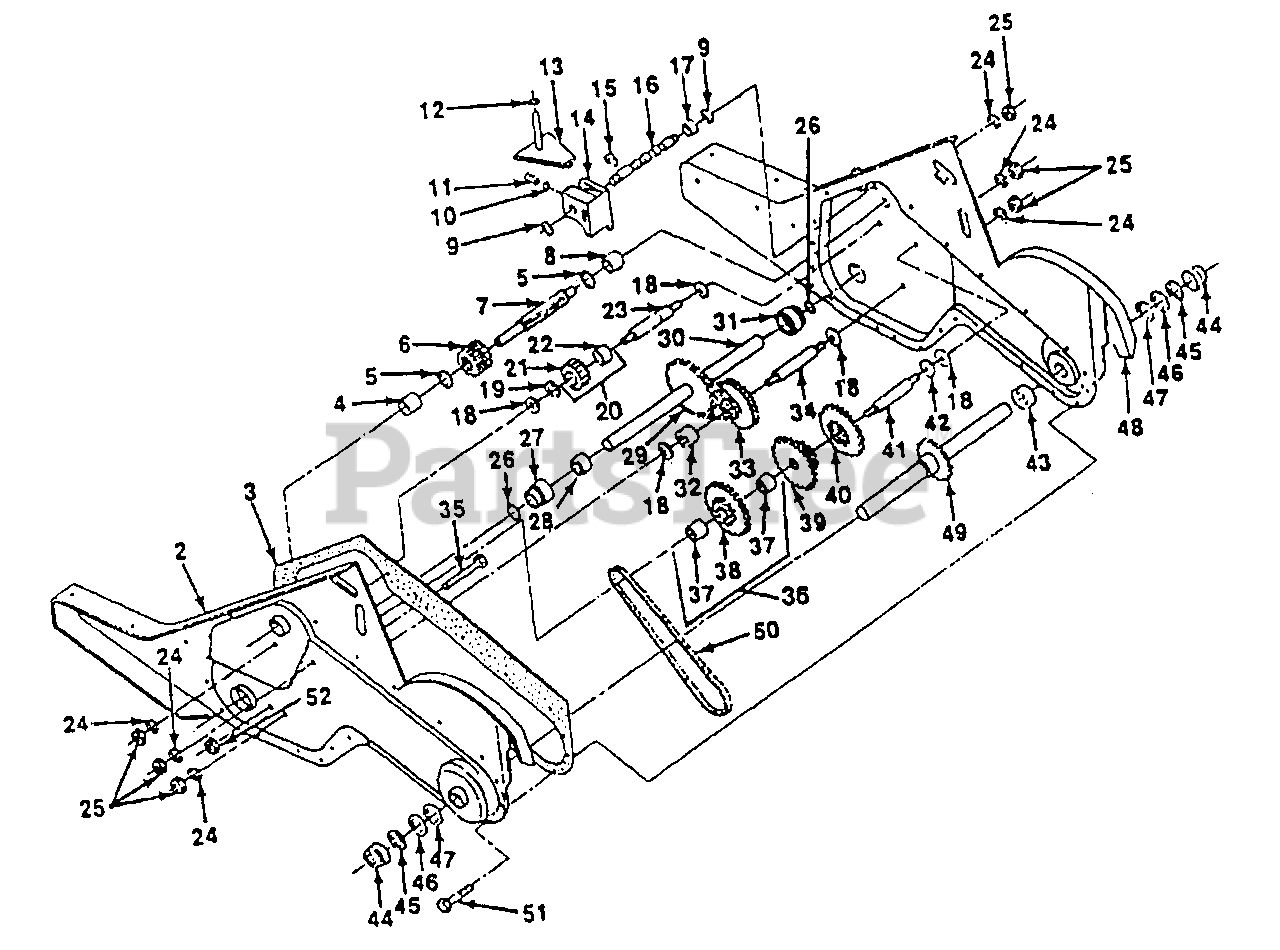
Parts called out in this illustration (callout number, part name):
1	Transmission Assembly (Inc. 2-52) (AYP part number)
2	Gearcase, L.H. w/Bearing (Inc. 4) (AYP part number)
3	Gasket, Gearcase (AYP part number)
4	Bearing, Needle (AYP part number)
5	Washer, Thrust 5/8 x 1.10 x 1/32 (AYP part number)
6	Pinion, Input (AYP part number)
7	Shaft, Input (AYP part number)
8	Bearing, Needle (AYP part number)
9	Washer, Seal (AYP part number)
10	Ball, Steel (AYP part number)
11	Spring, Shift, Fork (AYP part number)
12	O-Ring (AYP part number)
13	Arm, Shift (AYP part number)
14	Fork, Shift
15	Ring, Klip (AYP part number)
16	Shaft, Shift (AYP part number)
17	Spacer, Split (AYP part number)
18	Washer (AYP part number)
19	Ring, Klip (AYP part number)
20	Gear, Assembly, Idler, Reverse (Includes Key Nos. 21 and 22)
21	Gear, Idler, Reverse (AYP part number)
22	Bearing, Needle (AYP part number)
23	Shaft, Idler, Reverse (AYP part number)
24	Washer, Lock 7/16 (AYP part number)
25	Nut, Hex 7/16-20 (AYP part number)
26	O-Ring (AYP part number)
27	Bearing, Shaft, Ground Drive (AYP part number)
28	Spacer 0.765 x 1.125 x 1.23 (AYP part number)
29	Chain #35-50 Pitch (AYP part number)
30	Ground Shaft Assembly (AYP part number)
31	Bearing, Shaft, Ground Drive (AYP part number)
32	Spacer 0.70 x 1.00 x 1.150 (AYP part number)
33	Sprocket and Gear Assembly (AYP part number)
34	Shaft, Reduction (2nd) (AYP part number)
35	Screw, Whiz, Lock 5/16-18 x 3-1/2 (AYP part number)
36	Sprocket Assembly w/Bearing (Includes Key Nos. 37 and 38) (AYP part number)
37	Bearing, Needle (AYP part number)
38	Sprocket, Tine (AYP part number)
39	Gear, Cluster, Red 1st & 2nd (AYP part number)
40	Gear, Reverse (AYP part number)
41	Shaft, Reduction (1st) (AYP part number)
42	Washer, Thrust (AYP part number)
43	Spacer 1.01 x 1.75 x 0.760
44	Cup, Formed (AYP part number)
45	Ring, Spiral (AYP part number)
46	Seal, Ring, Rubber (AYP part number)
47	Seal, Oil (AYP part number)
48	Gearcase, R.H. w/Bearing (AYP part number)
49	Shaft, Tine (AYP part number)
50	Chain, Roller #50-50 Pitch (AYP part number)
51	Screw 1/4-20 x 1/2 (AYP part number)
52	Nut, Hex 5/16-18 (AYP part number)
